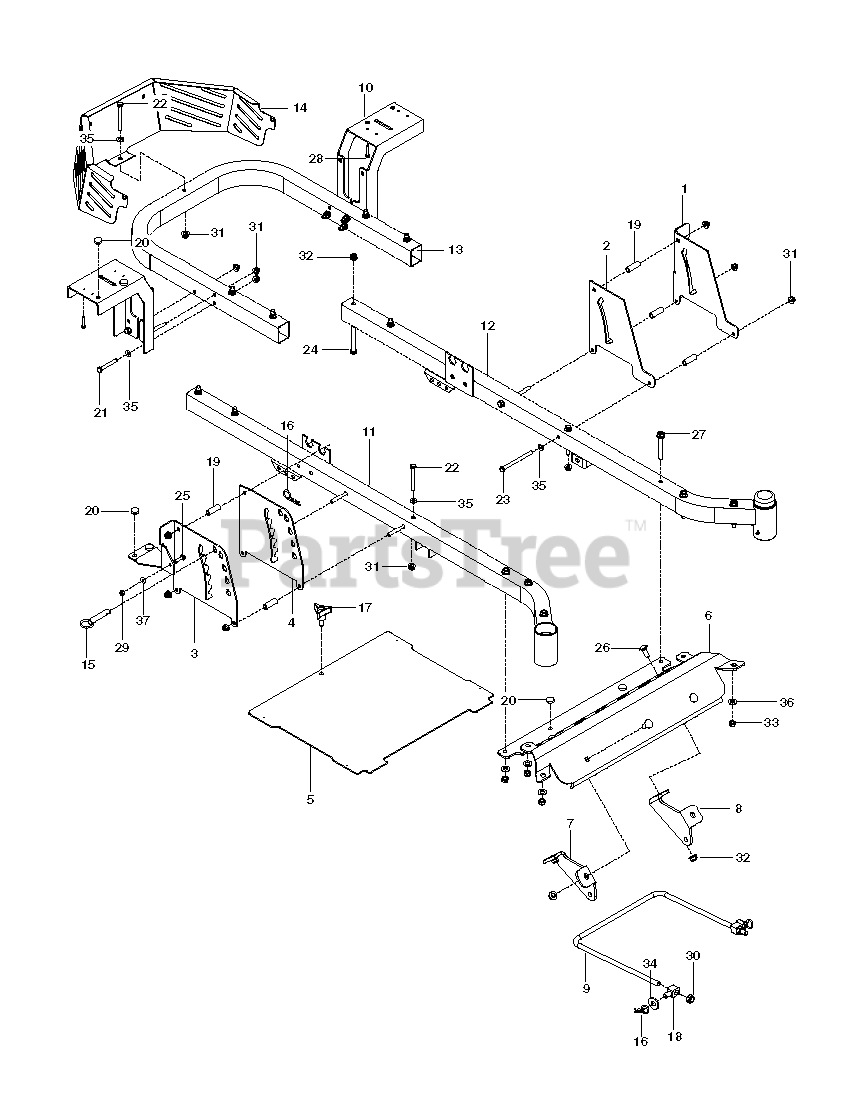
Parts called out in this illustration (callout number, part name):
1	PLATE, OUTER BRAKE, BLACK
2	PLATE, BRAKE LATCH, BLACK
4	PLATE, DECK HEIGHT, BLACK
5	PLATE, FOOT W/DECALS KZ
6	FOOT REST, MED BLUE
7	MOUNT, STRUT, RT, BLK
8	MOUNT, STRUT, LT, BLK
9	LINK, FRONT SUSP.
10	SUPPORT, FENDER, BLACK
11	FRAME, RT, BLUE
12	FRAME, LT, BLUE
13	FRAME TUBE, REAR BLUE
14	GUARD, REAR, BLUE
15	HITCH PIN
16	HAIRPIN #4
17	KNOB W/STUD
19	SPACER, .334 ID X .5 OD X 1.5
20	GROMMET, BUMPER
21	CAPSCREW
22	HCS 5/16C X 2-3/4
23	HCS 5/16C X 4
24	HCS 3/8C X 3
25	HCS 1/4C X 1
26	RHSNB 3/8C X 1
27	ENGINE BOLT, SPECIAL
28	SCR #10-12X1-1/2HEX WASH HD ZD
29	NUT 1/4-20 NYLOC
30	7/16-14 HEX NUT W/NYL RING ZD
31	5/16-18 NYLOC FLANGE NUT
32	NUT 3/8-16 HEX FLG NYLOC ZD
33	NUT HEX 3/8-16 NYLON, THIN
34	WASH USS FLAT 1/2
35	FLAT WASHER 5/16 SAE
36	WASHER 3/8 FLAT
37	WASHER 1/4 SAE
